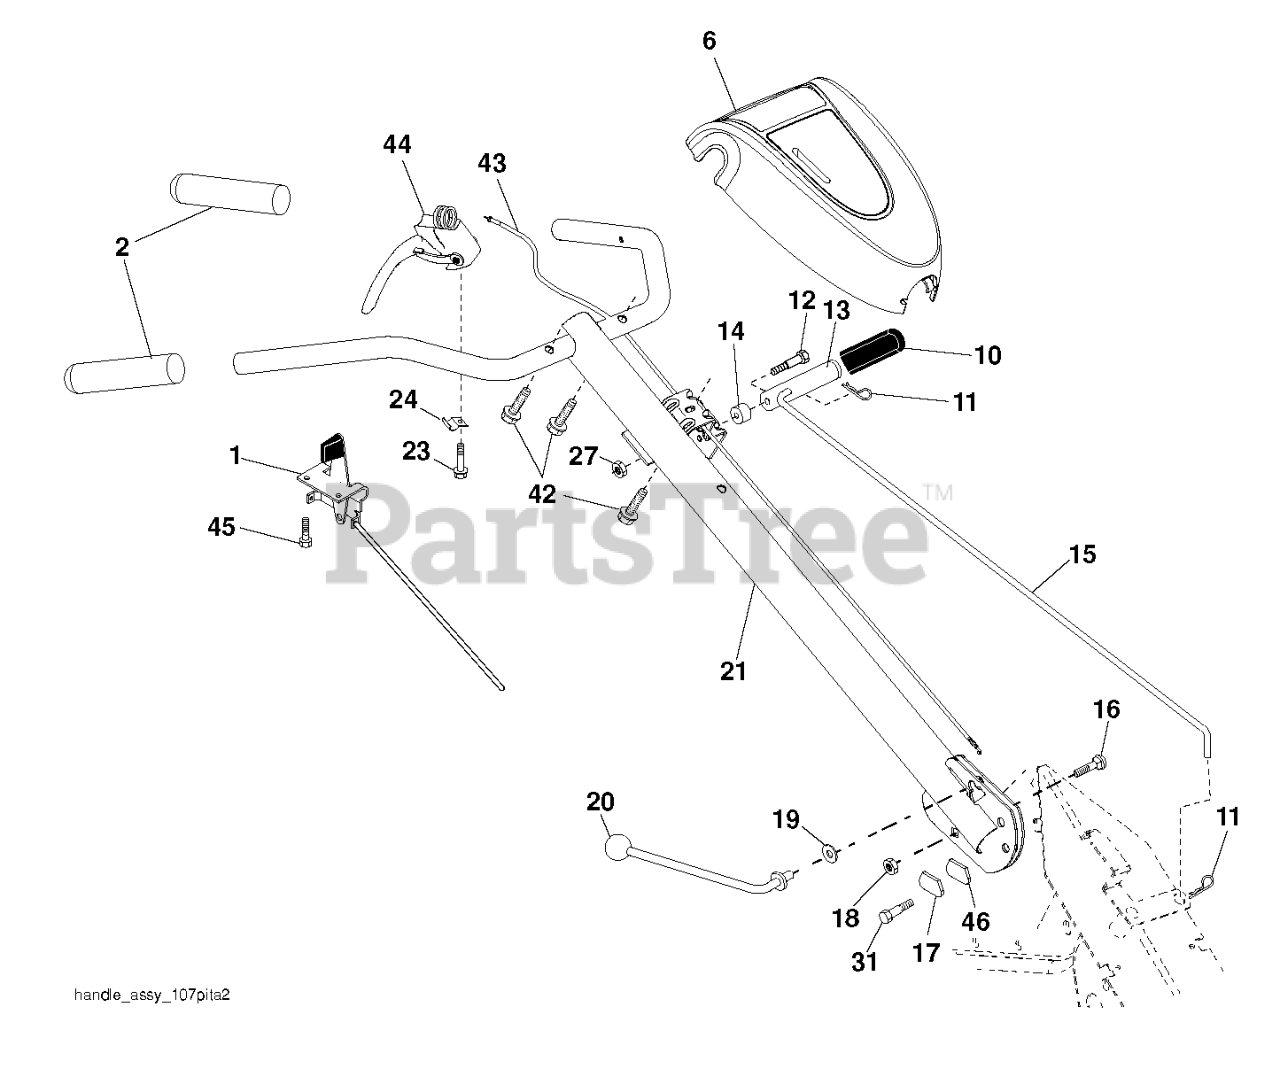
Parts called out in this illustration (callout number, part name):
1	RP.CONTROL.THROTTLE.47.W/Z.BEN
2	GRIP.1X5.06
6	CONSOLE.GREY.W/THROT.TR530
10	GRIP T
11	RETAINER M
12	SHOULDER BOLT ST
13	HANDLE.SHIFT.TILLER.498
14	GROMMET.RUBBER.CRT.TILLER
15	ROD.SHIFT.YARD PRO.UNIVERSAL.
16	BOLT D
17	LOCK.HANDLE.CRT
19	WASHER CRT
20	LEVER.LOCK.CRT
21	HANDLE.ASM.HUSQ/P.PRO.GREY
23	TAPPING SCREW
24	CLIP.PLATED
27	NUT T
31	BOLT.PIVOT
42	SCREW.#10 X 0.750.BOS
43	CABLE.HANDLE.TINE.CONT.RT.CE
44	CONTROL.HANDLE.TWO.FUNCTION.CE
45	SCREW.#10 X 0.500
46	LOCK HANDLE
